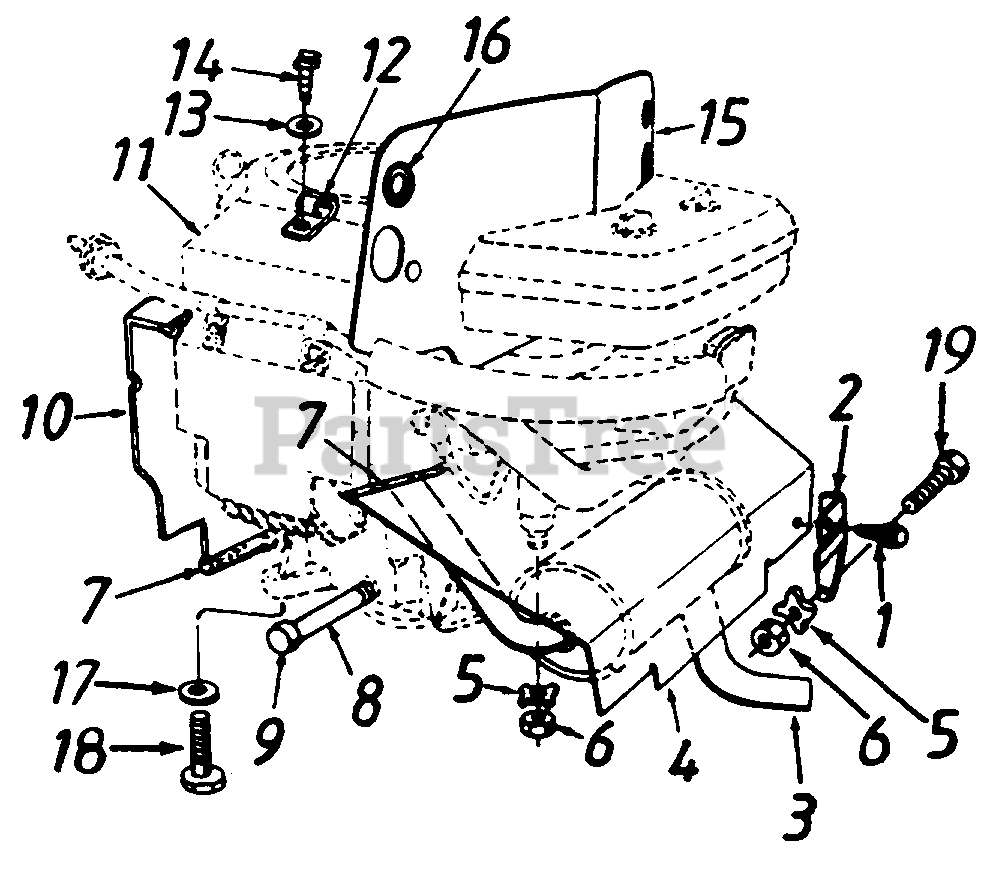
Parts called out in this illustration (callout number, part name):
1	Hex AB-Tap Scr. 1/4 x .62"
3	Muffler
4	Front Heat Shield
5	Spec. L-Wash. 5/16 x .88"
6	Hex Nut 5/16-18 Thd.
7	Trim Strip 12" Lg.
8	Pipe Nipple
9	Oil Drain Cap
10	Rear Baffle
11	Engine
12	Clamp
13	Fl-Wash. .188" I.D. x .438"
14	Truss Mach. AB-Tap Scr. #10 x .5" Lg.
15	Heat Shield
16	Rubber Grommet
17	Fl-Wash. .406" I.D. x 1-1/4" O.D.
18	Hex L-Wash. TT-Tap Scr. 3/8-16 x 1.5" Lg.
19	Hex Bolt 5/16-18 x 5/8" Lg.
